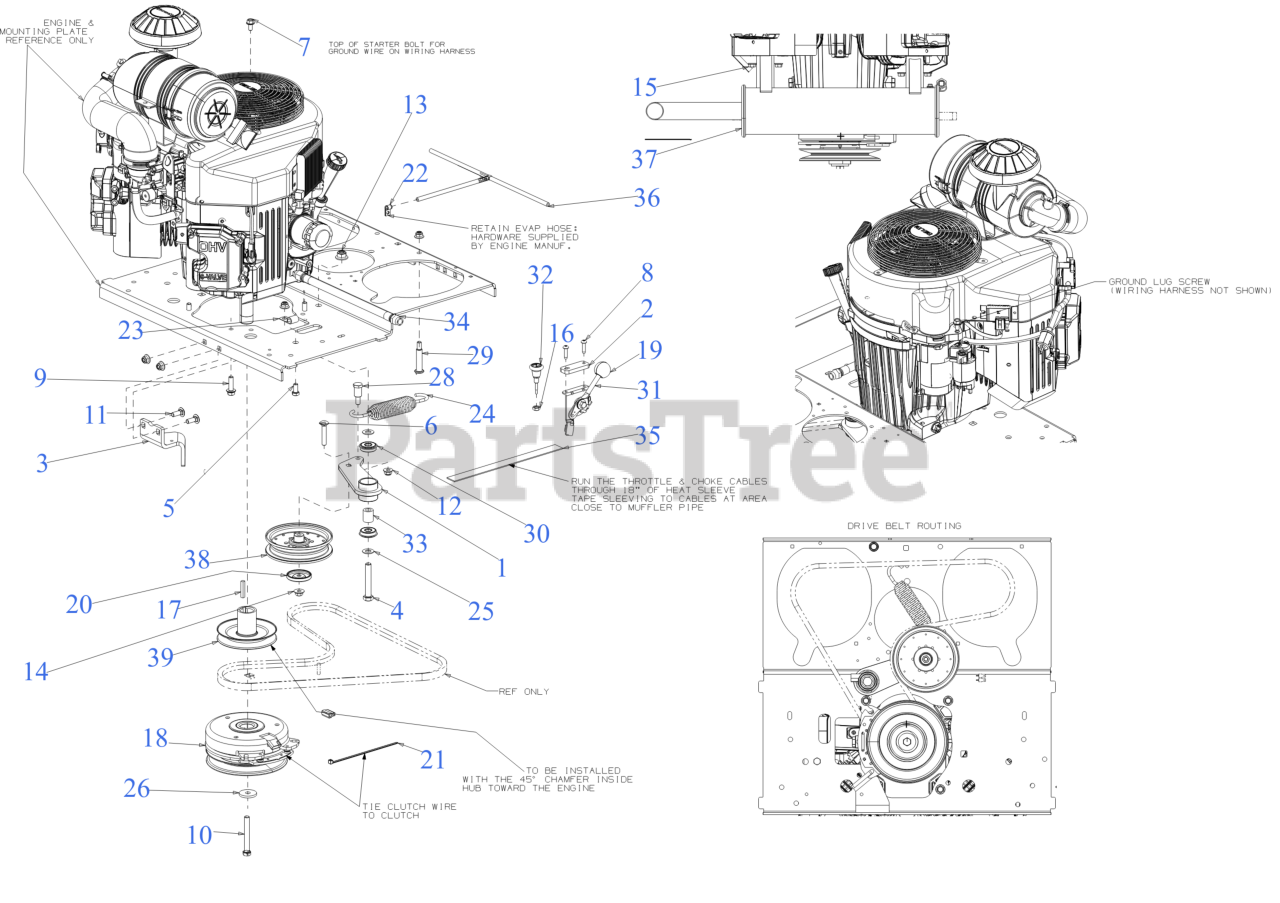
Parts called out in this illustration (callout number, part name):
1	IDLER BRACKET
3	CLUTCH RETAINER BRACKET
4	SCREW-HEX 1/2-13 x 3.00
5	HEX SCREW 3/8-16 x .75
6	CARRIAGE BOLT 3/8-16 x 2
7	SCREW M8 x 1.25 x 16MM GR8.8
8	SCREW 1/4-20 x 1.0
9	SCREW 3/8-16 x 1.25 GR5
10	SCREW 7/16-20 x 3.25 GR5
11	CARRIAGE BOLT 3/8-16 x 1.00 GR5
14	FLANGE LOCK NUT
15	HEX FLANGE NUT
16	HEX JAM NUT 3/8X24
17	SQUARE KEY 1/4 x 1.50
18	ELECTRIC PTO CLUTCH
20	PULLEY CAP
21	7" CABLE TIE
22	MOUNTING CLAMP
23	J TYPE CLIP
24	EXTENSION SPRING W/HOOK
25	FLAT WASHER .510 x .995
26	FLAT WASHER .45 x 1.5 x .172 HT
28	SHOULDER SCREW .625 x .875 x 3/18
29	SHOULDER BOLT (.50 X 2.0 x 3/8 -16)
30	ROLLER BEARING .5X1.37X.44
31	THROTTLE CABLE 59"
32	CHOKE CABLE
33	SPACER 0.51 x 0.88 x 1.00
34	OIL DRAIN HOSE
35	HEAT SHIELD 24"
36	ROLLOVER VENT HOSE ASSEMBLY
37	MUFFLER - KAWASAKI 1000
38	FLAT IDLER PULLEY
39	ENGINE PULLEY
